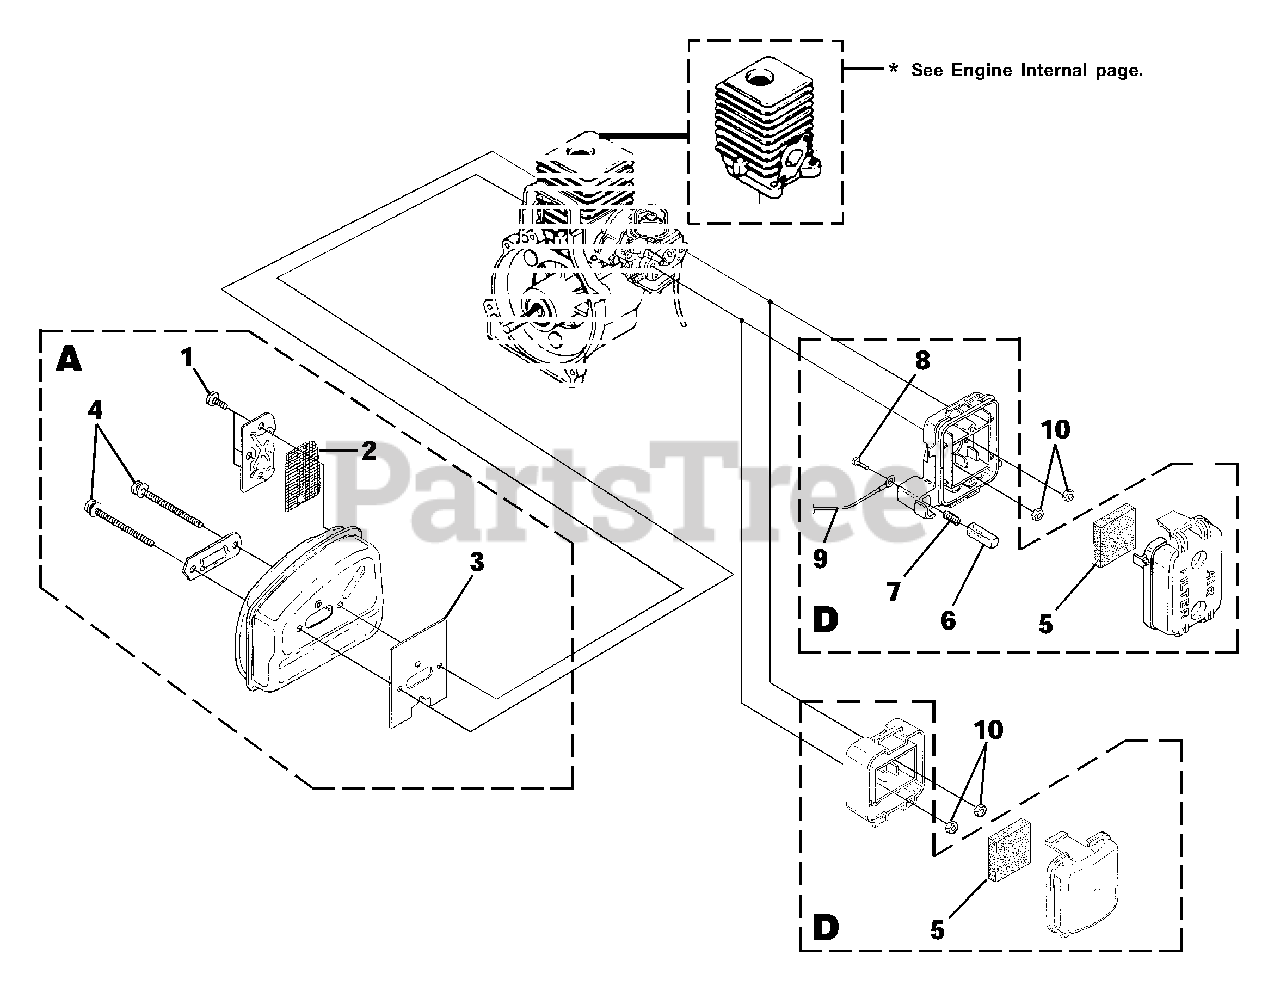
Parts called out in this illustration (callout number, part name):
1	SCREW, Taptite- (8-32 X 3/8")
2	SCREEN-Spark
3	GASKET-Muffler
4	SCREW, Truss Hd. - (10-24 X 2.188)
5	FILTER-Air
5	FILTER-AIR
6	BUTTON-Switch
7	SPRING-Compression
8	SCREW-Thread Form (6-19 x 1/2")
9	LEAD-Electrical
10	NUT-Hex (10-24)
A	MUFFLER ASSY.
D	AIR FILTER KIT (Non-Clutch)
D	AIR FILTER KIT (Clutch)
